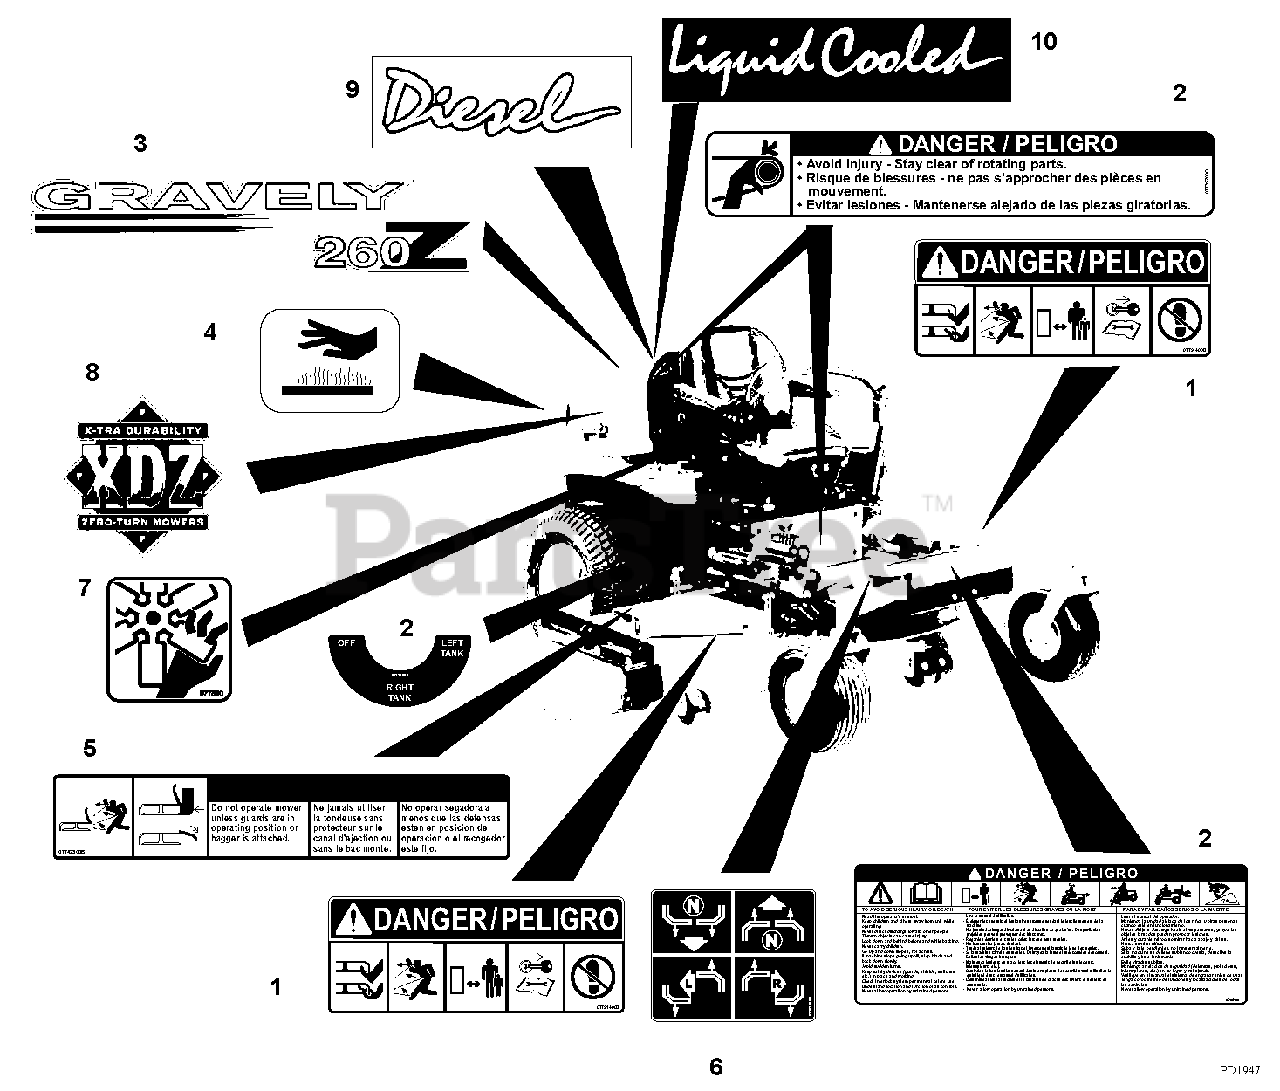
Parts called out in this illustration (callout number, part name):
1	Decal, Mower Pan Head Danger
2	Set, Decal-Common Danger/Fuel
3	Decal, PM-260Z Hood (992156)
4	Decal, Hot Surface
5	Decal, Warning
6	Decal, Instructional
7	Decal, Danger Fan
8	Decal, XDZ
9	Decal, Diesel (992156, 158)
10	Decal, Liquid Cooled
